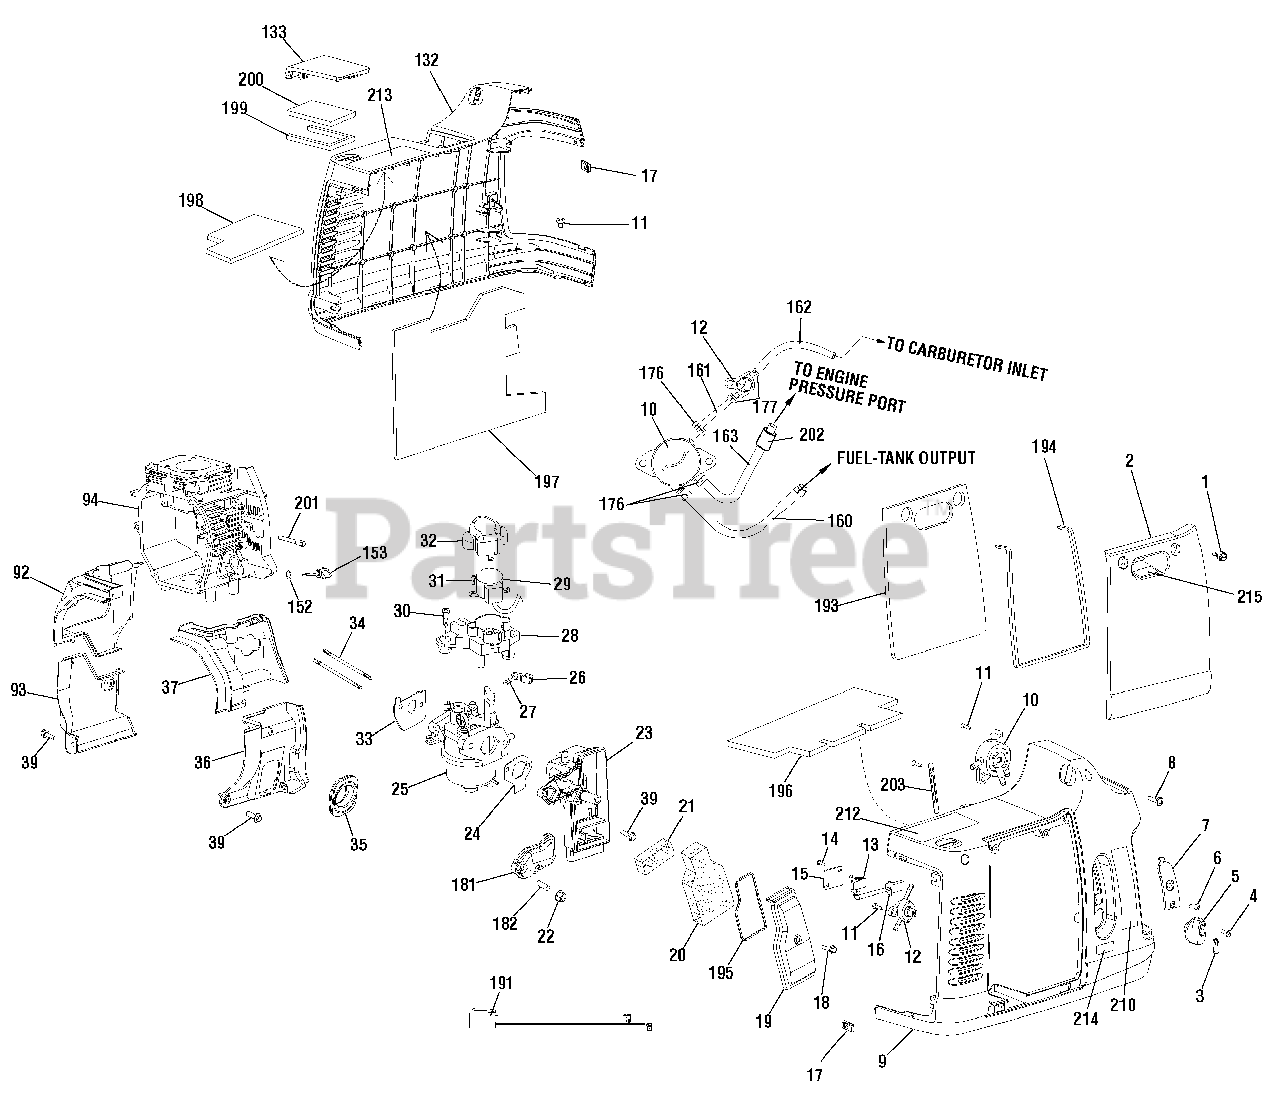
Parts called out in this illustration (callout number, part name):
4	BOLT
11	SCREW
14	BOLT
15	COVER-SWITCH
16	CONNECTION
17	NUT
19	COVER-AIR CLEANER
20	FILTER-A/C FOAM
21	FILTER-A/C FOAM
22	NUT
23	BASE-AIR CLEANER
24	GASKET-AIR CLEANER
27	SPRING
30	BOLT
31	BOLT
35	SEAL-RUBBER
36	DEFLECTOR
37	DEFLECTOR
92	DEFLECTOR
93	DEFLECTOR
94	CRANKCASE
133	COVER-SPARK PLUG
176	CLAMP
177	CLAMP
181	COVER-AIR CLEANER
182	SLEEVE
193	FOAM
194	SEAL
195	SEAL
196	FOAM
197	FOAM
198	FOAM
199	SEAL
200	FOAM
201	CYLINDER-BREATHER TUBE
202	TUBE
203	BRACKET
